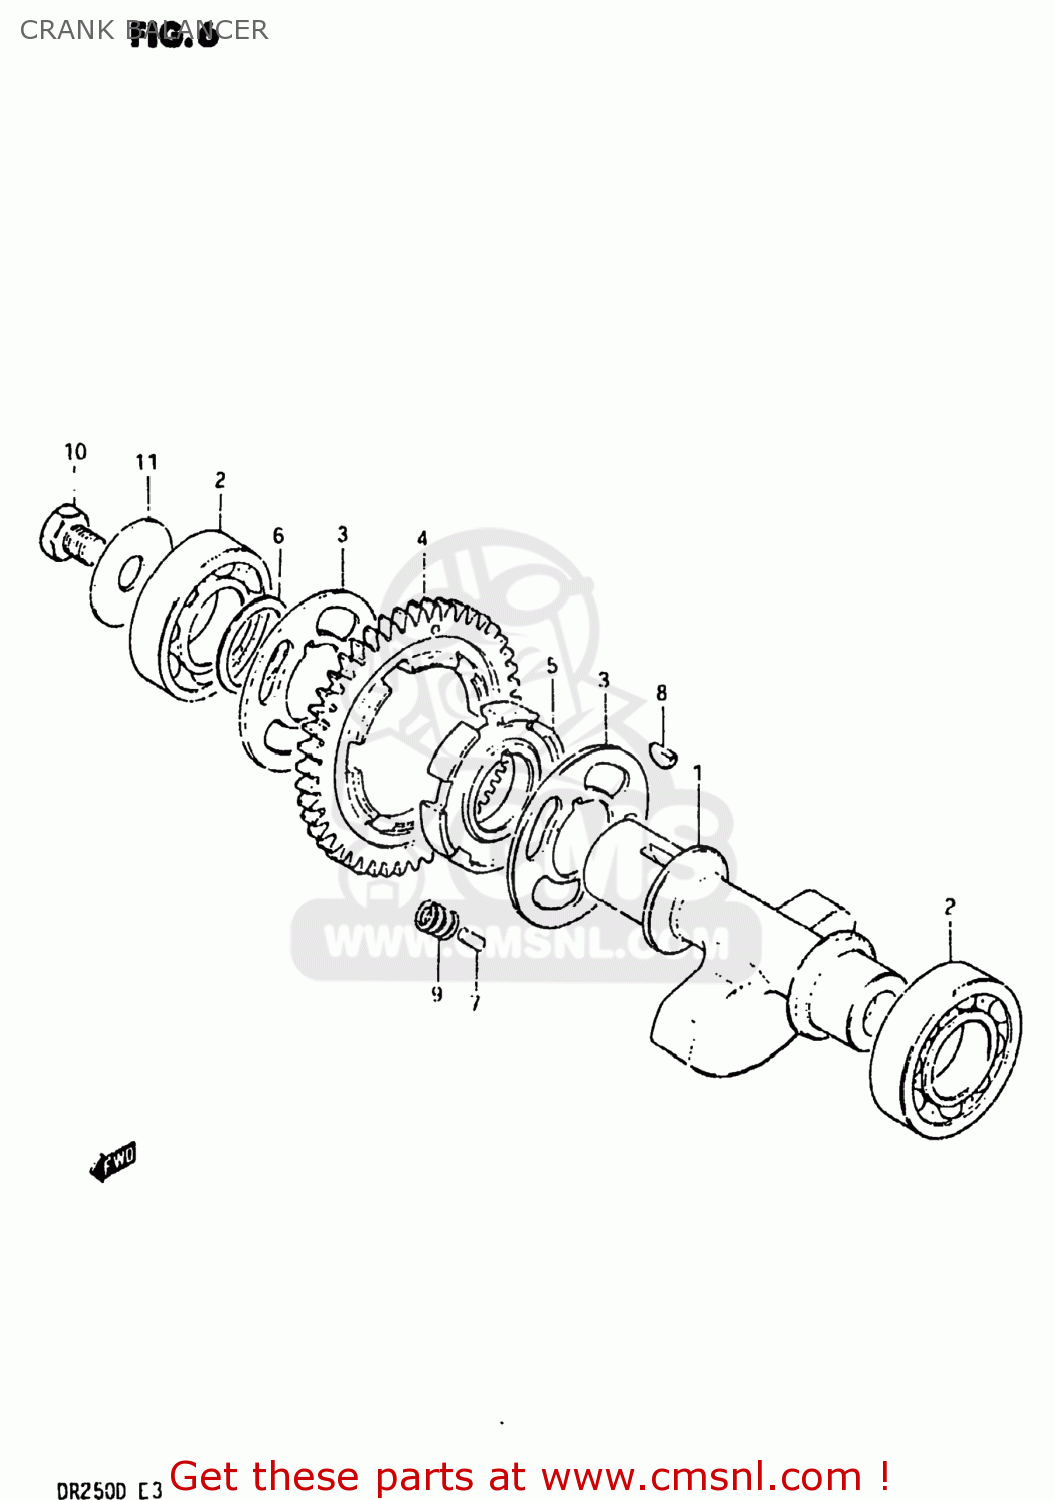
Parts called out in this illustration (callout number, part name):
1	BALANCER,CRANKSHAFT
2	BEARING
3	WASHER
4	GEAR,CRANK BAL DRIVEN(NT:46)
5	RACE,CRK BAL DRIVEN GR INNER
6	SHIM
7	PIN
8	KEY 4MM
9	SPRING
10	BOLT ,12X16
11	WASHER
